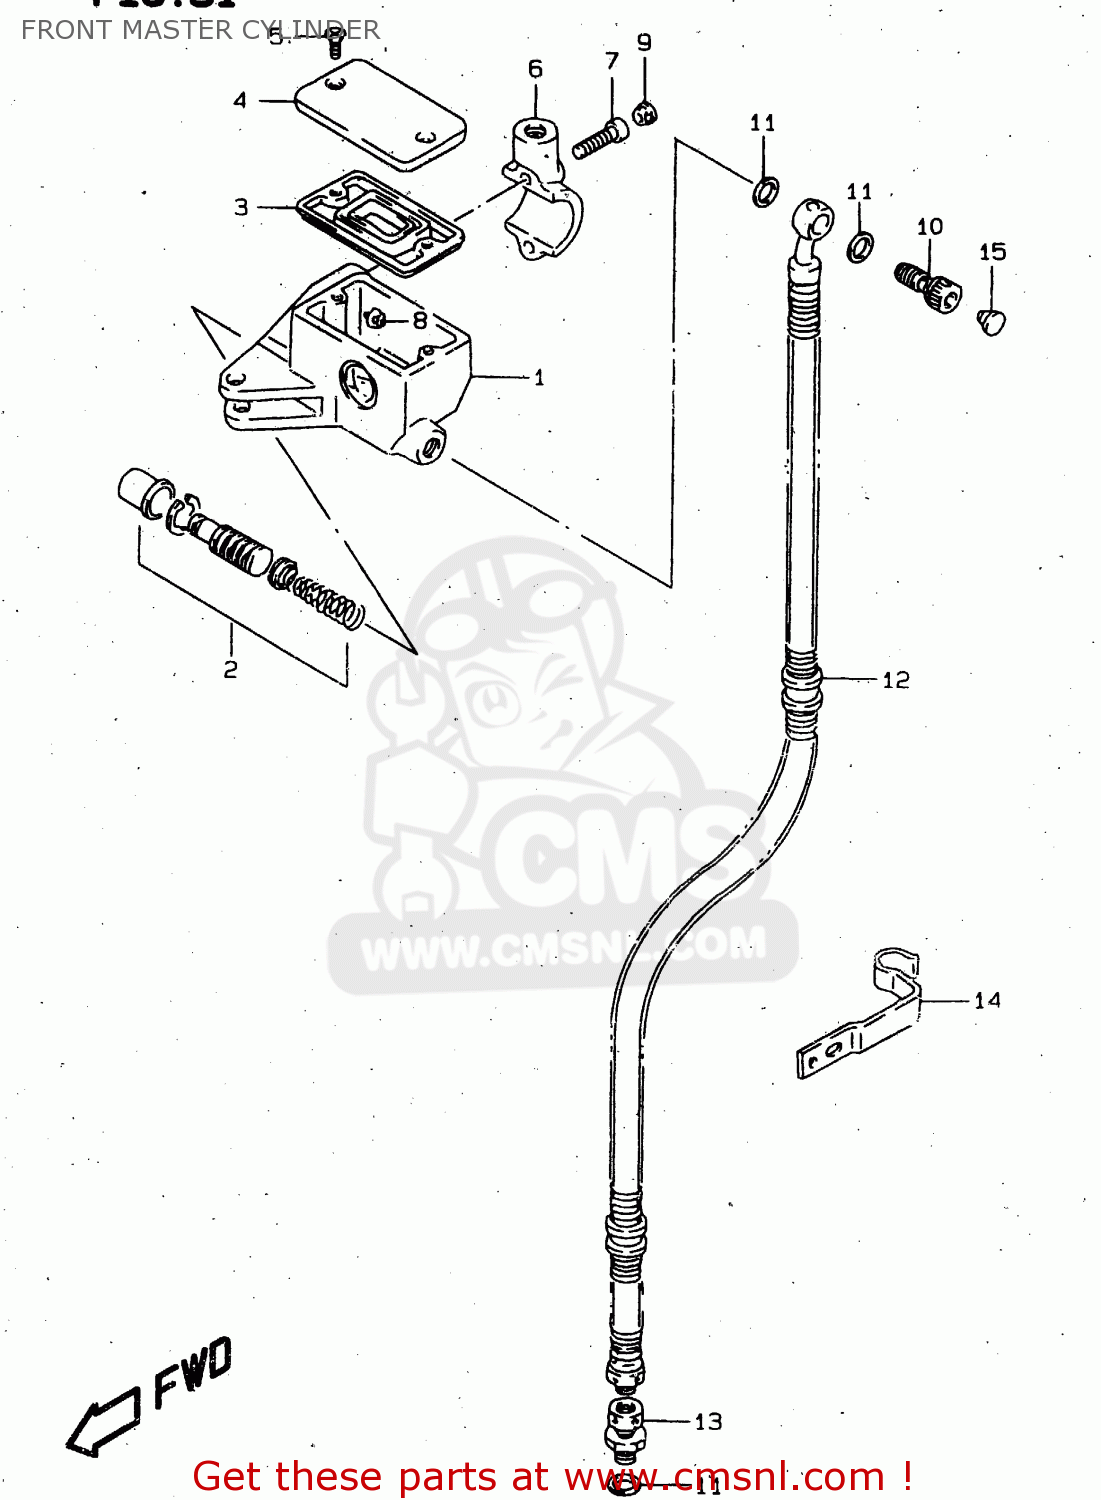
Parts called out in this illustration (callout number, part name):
1	CYLINDER ASSY,FR MASTER
2	PISTON/CUP SET
3	4
4	CAP
5	SCREW
6	HOLDER
7	BOLT
8	PROTECTOR
9	CAP(OD:10)
10	BOLT UNION
11	WASHER(10X15X1.5)
12	HOSE,FR BRAKE
13	ADAPTER,BRAKE HOSE
14	GUIDE,BRAKE HOSE
15	CAP(OD:12)
